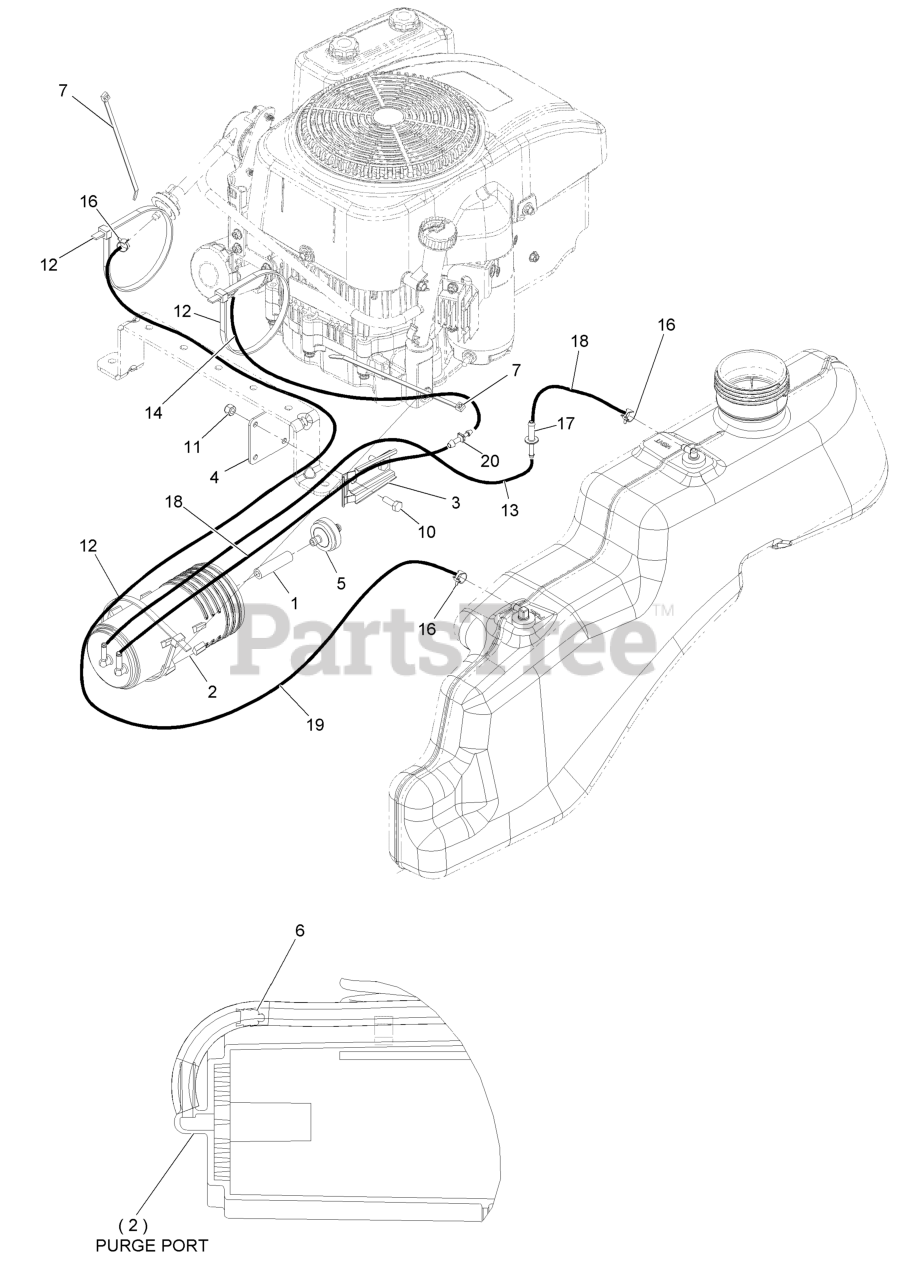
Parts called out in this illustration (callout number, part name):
1	HOSE-FUEL
2	CANISTER-CARBON, 800CC
3	BRACKET-CANISTER, CARBON
4	PLATE-ADAPTER
5	FILTER-FUEL, INLINE
6	CARTRIDGE-VALVE, CHECK
7	TIE-CABLE
10	SCREW-HH
11	NUT-LOCK, NI
12	TIE-CABLE
14	HOSE-FUEL
16	CLAMP-HOSE
17	ADAPTOR-ORIFICE
18	HOSE-FUEL
19	HOSE-FUEL
20	FITTING-STRAIGHT
